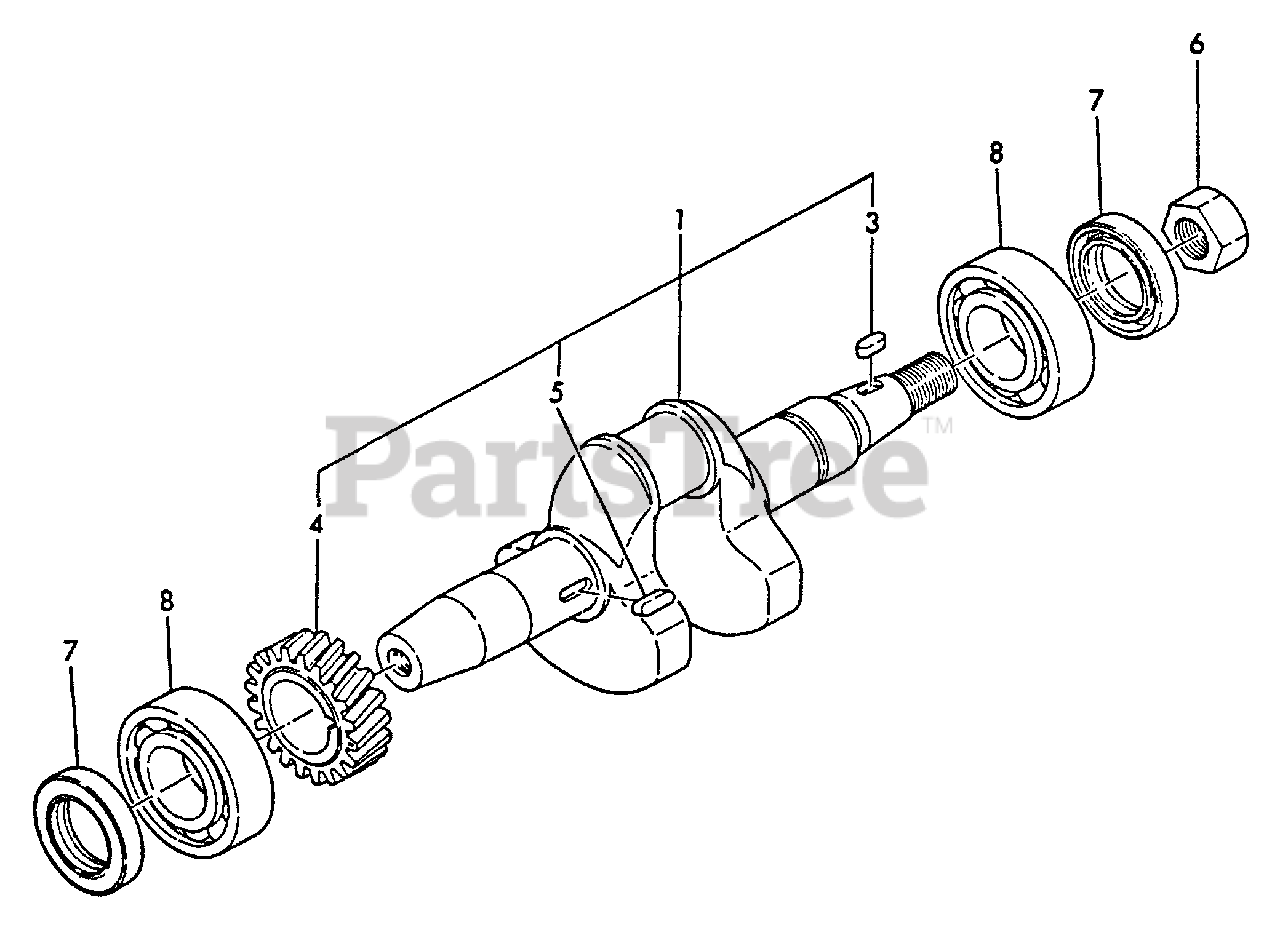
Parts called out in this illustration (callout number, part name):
1	CRANKSHAFT ASSY
3	KEY - 4×10
4	GEAR, CRANKSHAFT
5	KEY 4×12
6	NUT - 14
7	SEAL, OIL
8	BEARING, BALL
